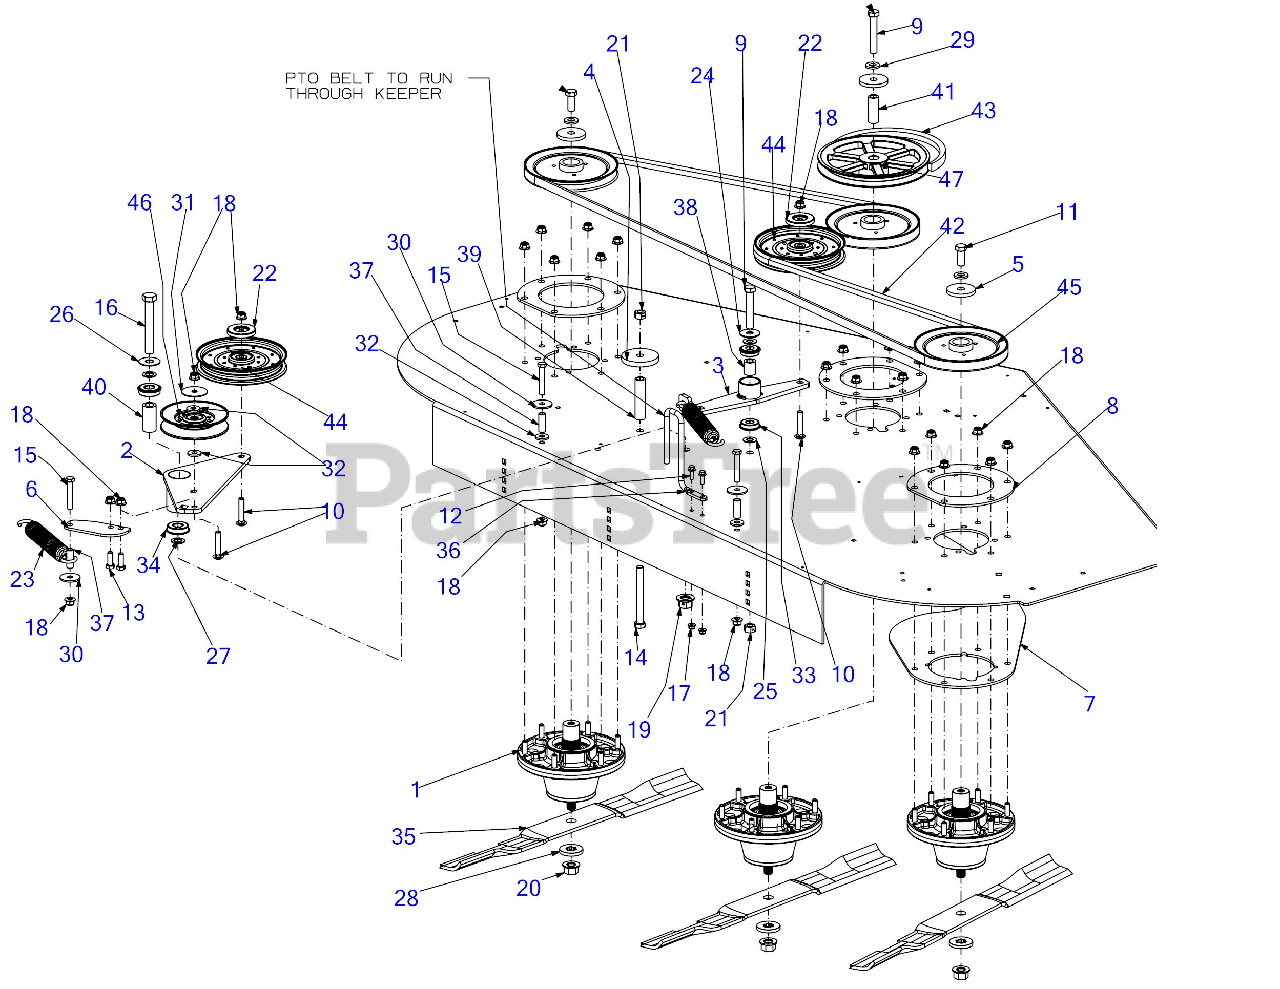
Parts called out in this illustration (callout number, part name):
1	SPINDLE ASSEMBLY
5	FLAT WASHER 0.531 X 2.125 X 0.25
8	SPINDLE SUPPORT BRACKET TOP/BTM
9	SCREW-HEX 1/2-13 X 3.00
10	CARRIAGE BOLT 3/8-16 x 2
11	SCREW 1/2-13 x 1.25 GR5
12	SCREW 1/4-20 x .75 GR5
13	SCREW 3/8-16 x 1 GR5
14	SCREW 1/2-13 x 4.5 GR 5
15	SCREW 3/8-16 x 2.25 GR5
16	SCREW 5/8-18 x 4.25 GR5
17	FLANGE LOCK NUT
20	FLANGE NUT - 5/8-18 GDE 8
21	HEX NUT CTR LK 1/2-13
22	PULLEY CAP
23	SPRING 1.25" DIA X 8.5" LONG
24	WASHER .51 x 1.5 x .07
25	FLAT WASHER .510 x 1.00 x .060
26	FLAT WASHER-.63IDX1.595ODX.62
27	FLAT WASHER
28	FLAT WASHER - SPECIAL
29	FLAT WASHER .531X1.060X.134
30	FLAT WASHER .406X1.500X.105
31	HUB CAP WASHER .406 x 1.92 x .060
32	FLAT WASHER .406ID X1.0 OD
33	ROLLER BEARING .5X1.37X.44
34	BALL BEARING
35	25" HI-LIFT BLADE
38	SPACER 0.51 X 0.88 X 1.00
40	SPACER 0.63 X 1.00 X 2.01
41	SPACER 0.51 X 0.75 X 2.12
43	V-BELT B-SEC X 113.4"
44	IDLER PULLEY
45	SPINDLE PULLEY 7"
46	IDLER PULLEY 5.06 OD
47	SPINDLE DRIVE PULLEY 8.347 DIA
